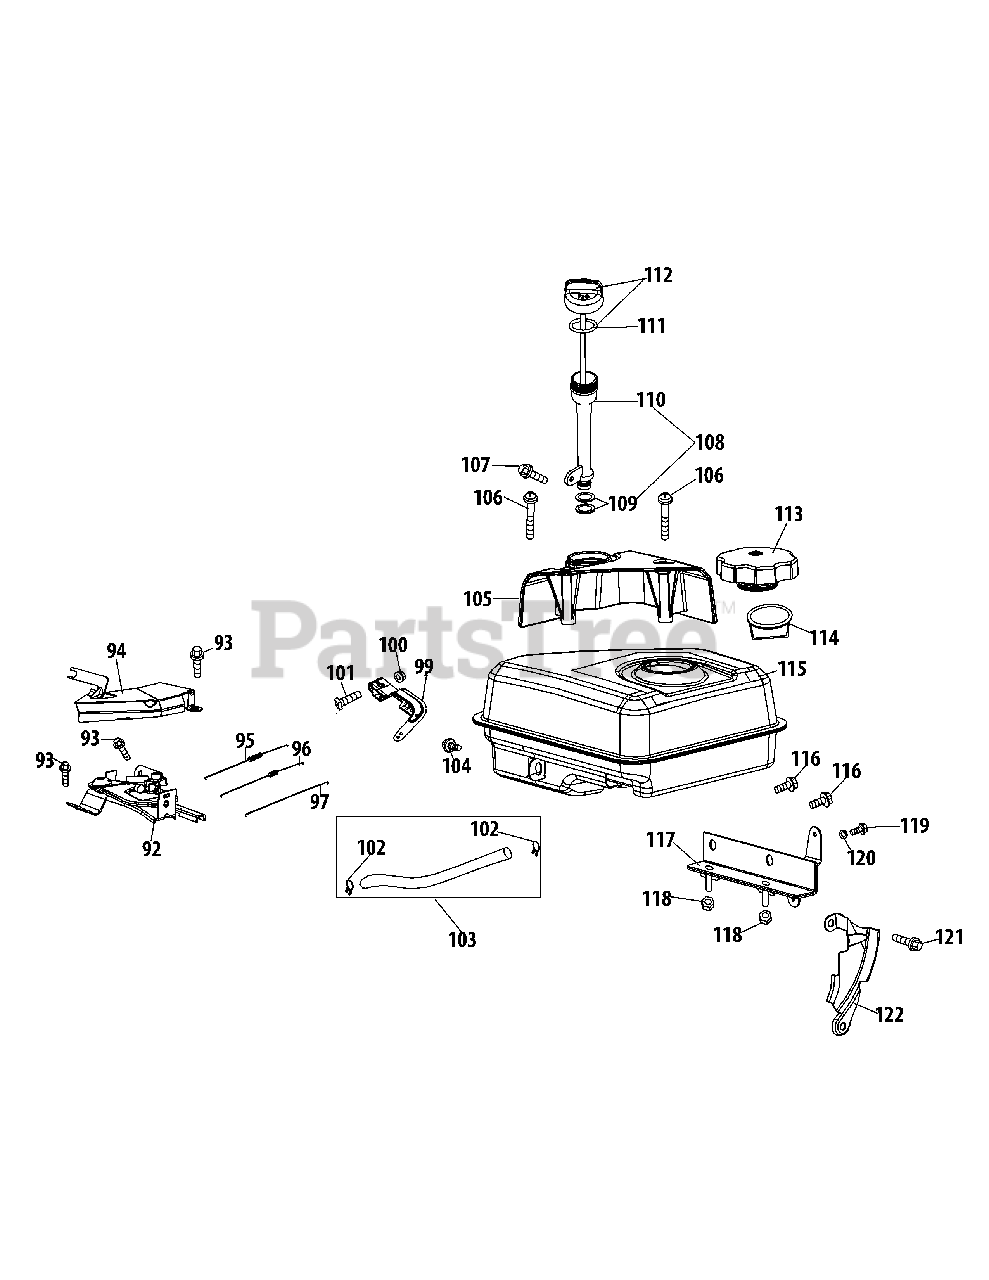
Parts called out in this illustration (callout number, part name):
92	Throttle Control Bracket
93	Bolt M6×12
94	Governor Shield
95	Governor Spring
96	Throttle Return Spring
97	Governor Rod
99	Governor Arm Bracket
100	Flange Nut M6
101	Governor Arm Bolt M6X21
102	Hose Clamp
103	Fuel Line Kit
104	Bolt M6×12
105	Engine Dipstick Cover
106	Engine Cover / Dipstick Bolt
107	Bolt M6×12
108	Oil Fill Tube Assembly
109	Fill Tube O-Ring
110	Dipstick Tube
111	Dipstick O-Ring
112	Dipstick Assembly
113	Fuel Cap
114	Fuel Level Indicator
115	Fuel Tank
116	Bolt:Flange M6X20
117	Switch Housing Mounting Bracket
118	Nut, M6
119	Screw M4×10
120	Washer
121	Bolt M6×20
122	Blower Housing Shield
